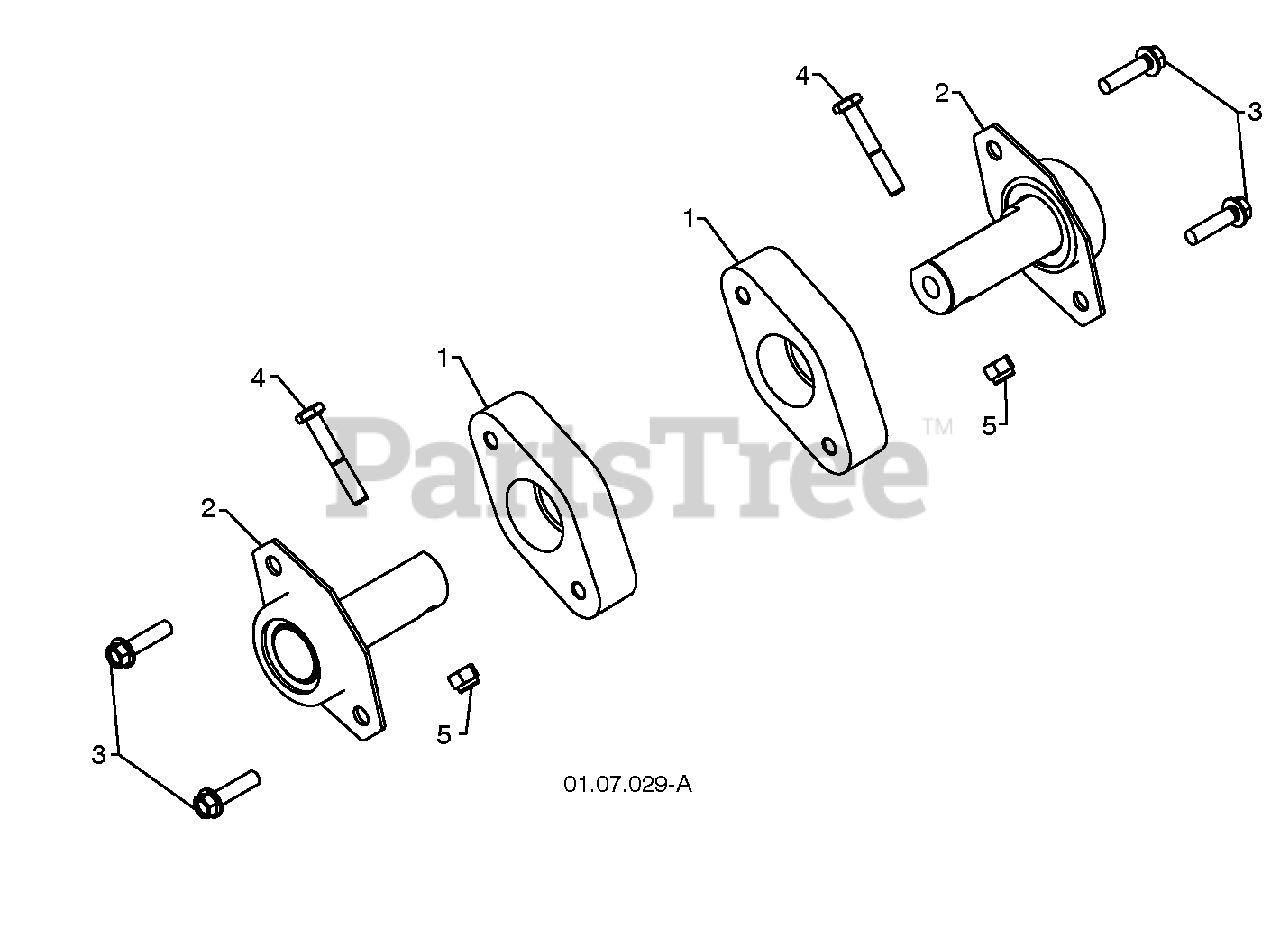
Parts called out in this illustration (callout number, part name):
1	PLASTIC RETAINER
2	AUGER BALL BEARING
3	SCREW 5/16-18 X 1.00
4	SCREW 1/4-20 X .625
5	NUT 1/4-20
